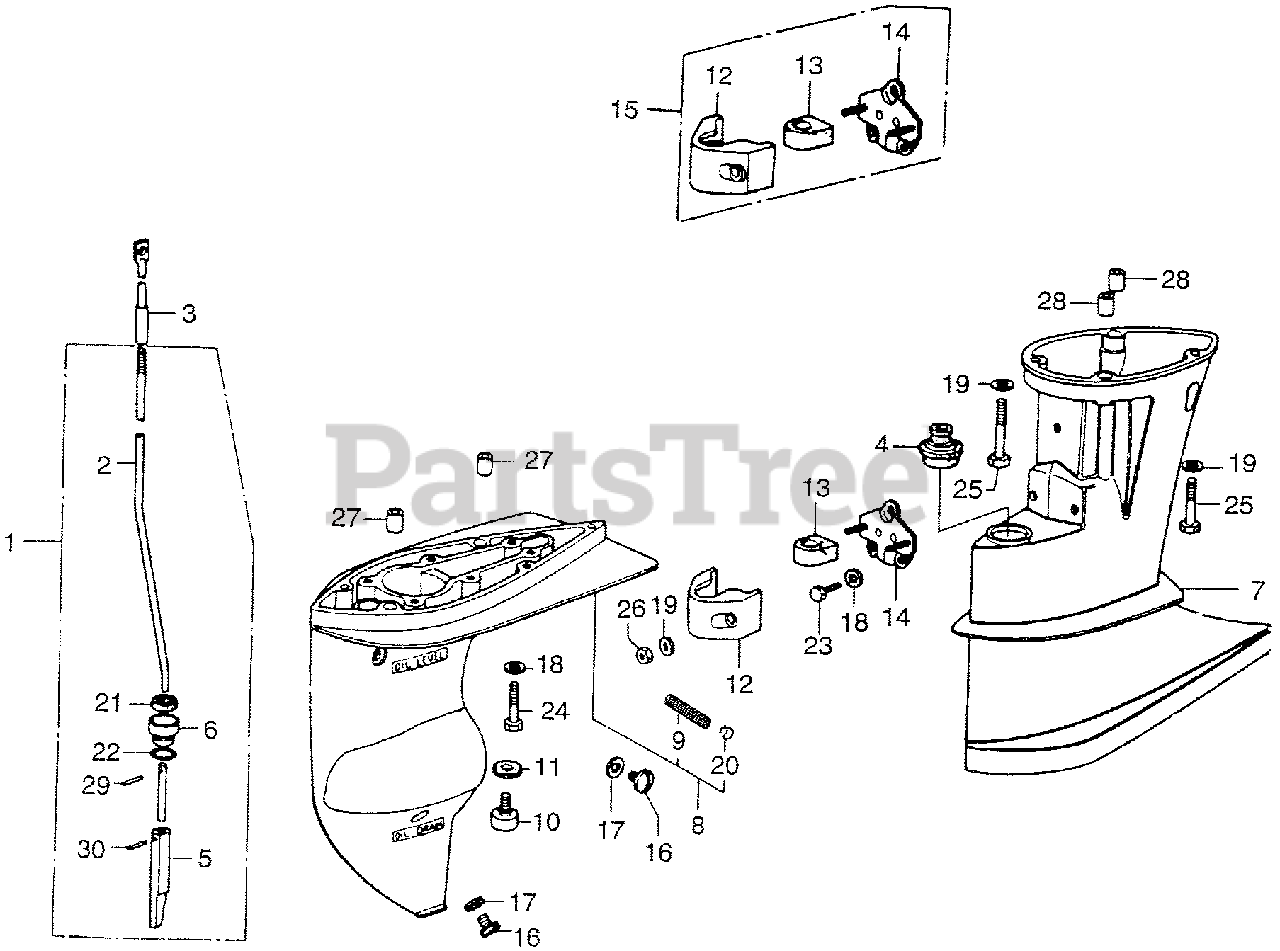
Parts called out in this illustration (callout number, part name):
1	ROD, SHIFT (NOT AVAILABLE)
2	ROD, SHIFT (LONG)
2	ROD, SHIFT (SHORT)
3	JOINT, CHANGE ROD (NOT AVAILABLE)
4	GROMMET, ROD
5	ROD, PUSH
6	HOLDER, SEAL (N/A: SEE ASSEMBLY)
7	CASE, EXTENSION *PB1* (DARK BLUE)
8	CASE, GEAR *PB1* (DARK BLUE)
9	SCREEN, WATER
10	METAL, ANODE
11	RUBBER, INSULATE (NOT AVAILABLE)
12	HOUSING, SETTING (LOWER) *PB1* (DARK BLUE)
12	HOUSING, SETTING (LOWER) *PB1* (DARK BLUE) (NOT AVAILABLE)
13	RUBBER, SETTING (LOWER)
14	PLATE, SETTING (LOWER)
15	SETTING (LOWER) *PB1* (DARK BLUE) (NOT AVAILABLE)
16	BOLT, OIL CHECK
17	WASHER C (8MM)
18	WASHER, PLAIN (6MM)
19	WASHER, PLAIN (8MM)
20	PLUG, SEALING (10MM)
21	SEAL, WATER (6MM)
22	O-RING (9.4X2.4)
23	BOLT, HEX. (6X12)
24	BOLT, HEX. (6X40)
25	BOLT, HEX. (8X50)
26	NUT, HEX. (8MM)
27	PIN A, DOWEL (8X10)
28	PIN A, DOWEL (10X14)
29	PIN, SPRING (2.5X12)
30	ROLLER (2.5X11.8)
